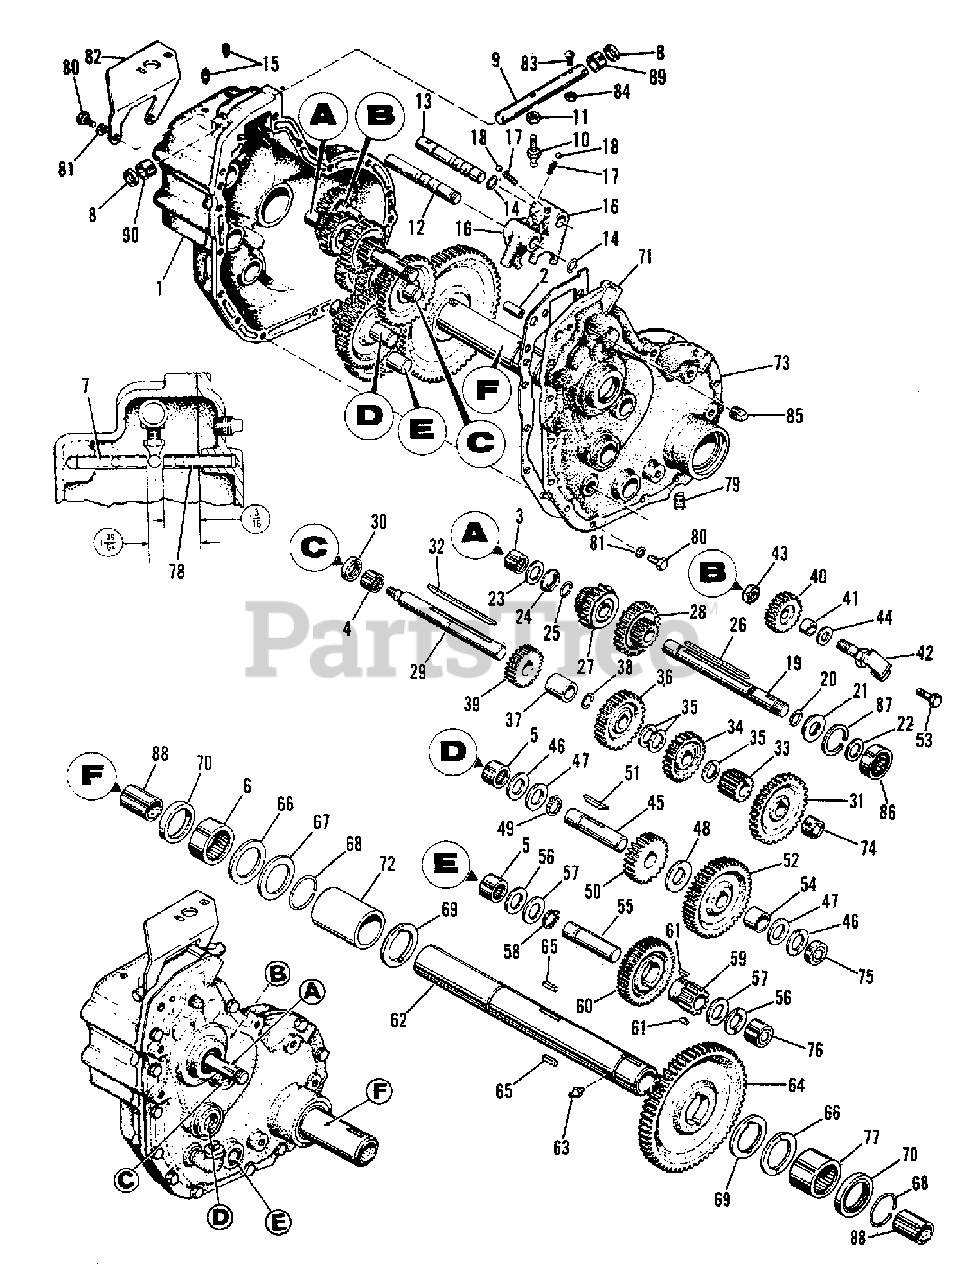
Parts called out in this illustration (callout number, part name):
1	CASE ASSEMBLY, Gear (Includes 1 Thru 7 & 90)
2	PIN, Roll
3	BEARING, Needle
4	BEARING, Needle
5	BEARING, Needle
6	BEARING, Needle
7	PIN, Roll
8	SEAL, Oil
9	ROD, Shift
10	STUD, Shift Stem (Prior S/N 25841001 & Up)
10	STEM, Shift (Eff. S/N 25841001 & Up)
11	NUT, Lock, 3/8NF (Prior S/N 25841001 & Up)
11	LOCKTITE (Eff. S/N 25841001 & Up)
12	SHAFT, Reverse Medium
13	SHAFT, High, Low
14	RING, Retaining
15	SETSCREW, 5/16NC x 1/2
16	FORK, Shift
18	BALL, Shift Lock
19	SHAFT, Pulley
20	RING, Retaining
25	RING, Retaining
27	PINION ASSEMBLY, Reverse II
28	PINION ASSEMBLY, I AND II
29	SHAFT, 1st Intermediate
30	SEAL, Oil
31	GEAR, Driven I
33	PINION, 1st Intermediate
34	PINION, Driven, III
36	GEAR, Driven II
38	RING, Retaining
39	PINION, Reverse
40	GEAR, Reverse
41	SPACER, Reverse Gear
42	PIN ASSEMBLY, Reverse Gear
43	NUT, Lock, 1/2NF
45	SHAFT, 2nd Intermediate
49	RING, Retaining
50	PINION, 2nd Intermediate
52	GEAR, 2nd Intermediate
53	CAPSCREW 3/8NC x 1-1/4
55	SHAFT, 3rd Intermediate
58	RING, Retaining
59	PINION, 3rd Intermediate
60	GEAR, 3rd Intermediate
61	KEY, Woodruff
62	TUBE ASSEMBLY, Axle (w/ Bushing)
63	FITTING, Lube (Package Of 10)
64	GEAR, Drive
68	RING, Snap
69	WASHER, Axle Tube
71	GASKET, Gear Case
72	SPACER, Axle Tube
73	COVER ASSEMBLY, Gear Case (Includes Items 74 Thru 78)
74	BEARING, Needle
75	BEARING, Needle
76	BEARING, Needle
77	BEARING, Needle
78	PIN ASSEMBLY, Roll
78	PIN, Roll, 3/8 x 2-1/4
79	PLUG, Pipe, 3/8
80	CAPSCREW, 5/16NC x 1
81	LOCKWASHER, 5/16
82	SUPPORT, Switch
83	BOLT, 5/16NC x 1
84	NUT, Jam, 5/16NC
85	PLUG, Pipe, 3/8
86	BEARING, Ball
87	RING, Retaining
